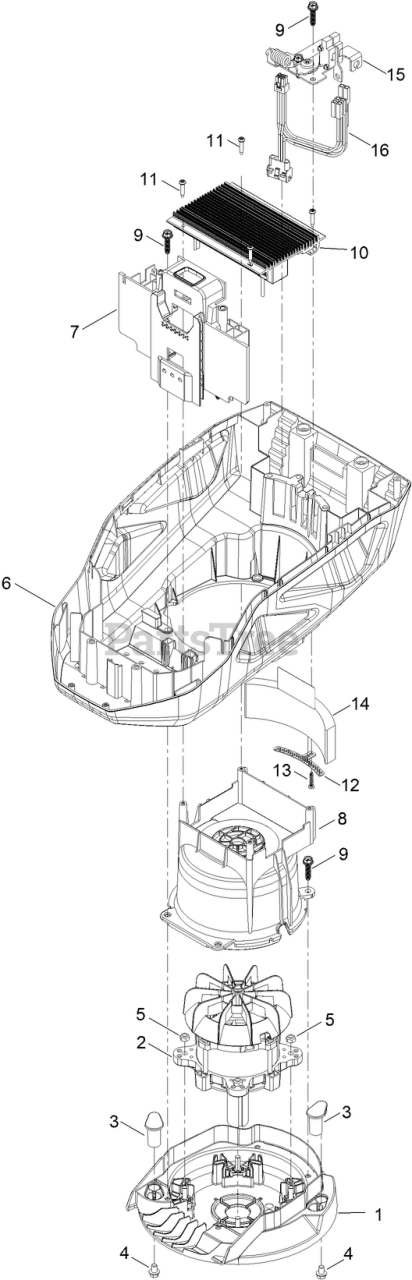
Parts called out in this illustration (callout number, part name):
1	BASE-MOUNT, MOTOR
2	MOTOR-2KW
3	INSERT-MOUNT, Motor
5	NUT-LOCK
6	SHROUD-LOWER
7	MOUNT-BATTERY
8	SHROUD-MOTOR
9	SCREW-FLANGE, PLASTIC
10	CONTROLLER-MOTOR
12	BRACKET-FOAM
13	SCREW-PLASTIC, PPH
15	BAIL SWITCH ASM
16	HARNESS-WIRE
